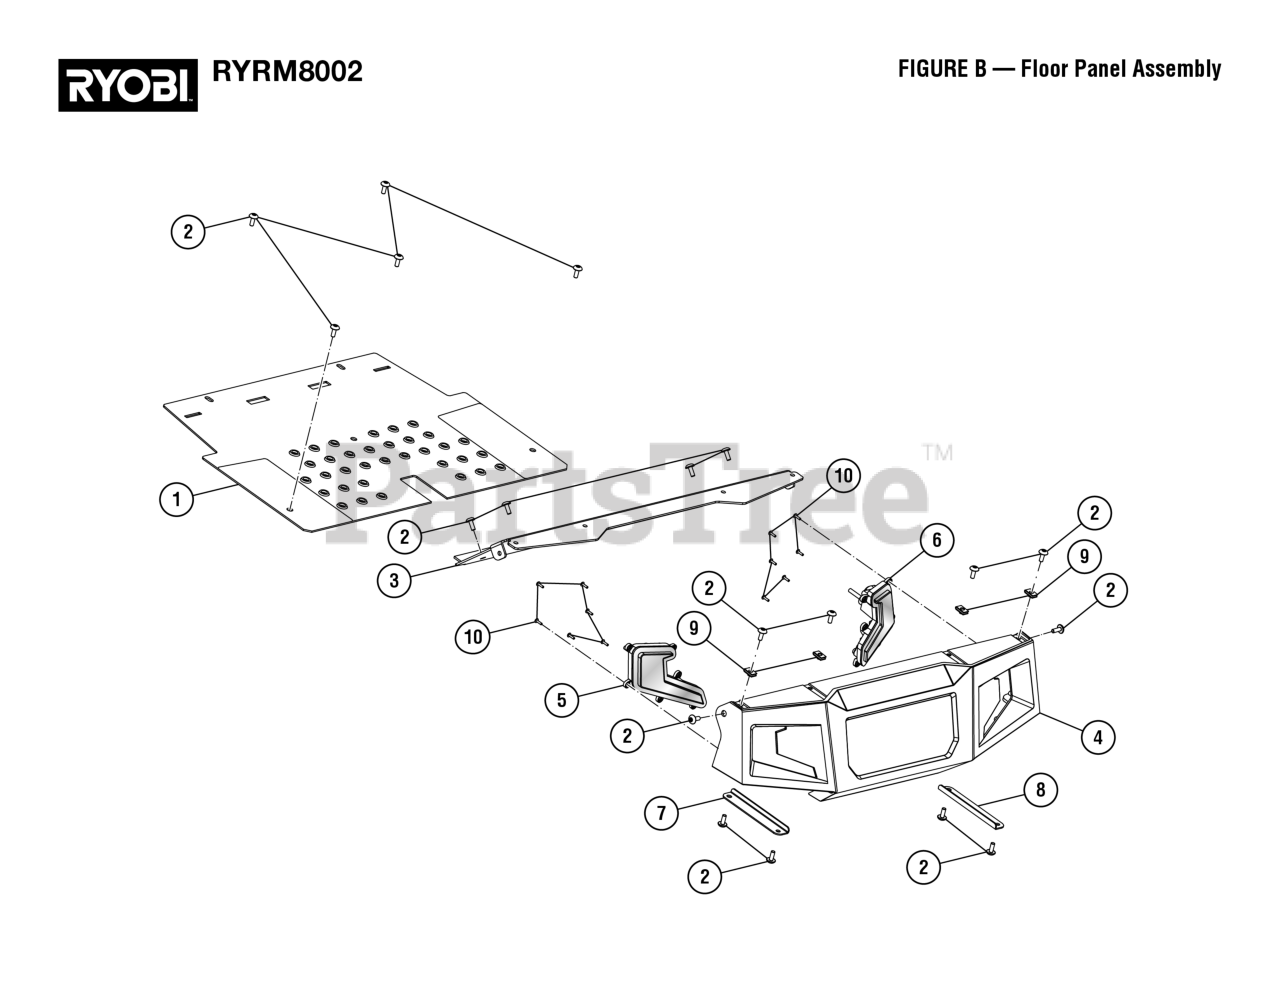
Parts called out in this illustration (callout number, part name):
1	Floor Board
2	Screw (M6 x 10 mm, Soc. Button Hd.)
3	Foot Rest
4	Front Fascia
5	LED Headlight Assemly (Right)
6	LED Headlight Assembly (Left)
7	Fascia Brace (Right)
8	Fascia Brace (Left)
9	Clip-On Nut (M6)
10	Screw (M3 x 12 mm, Pan Hd.)
